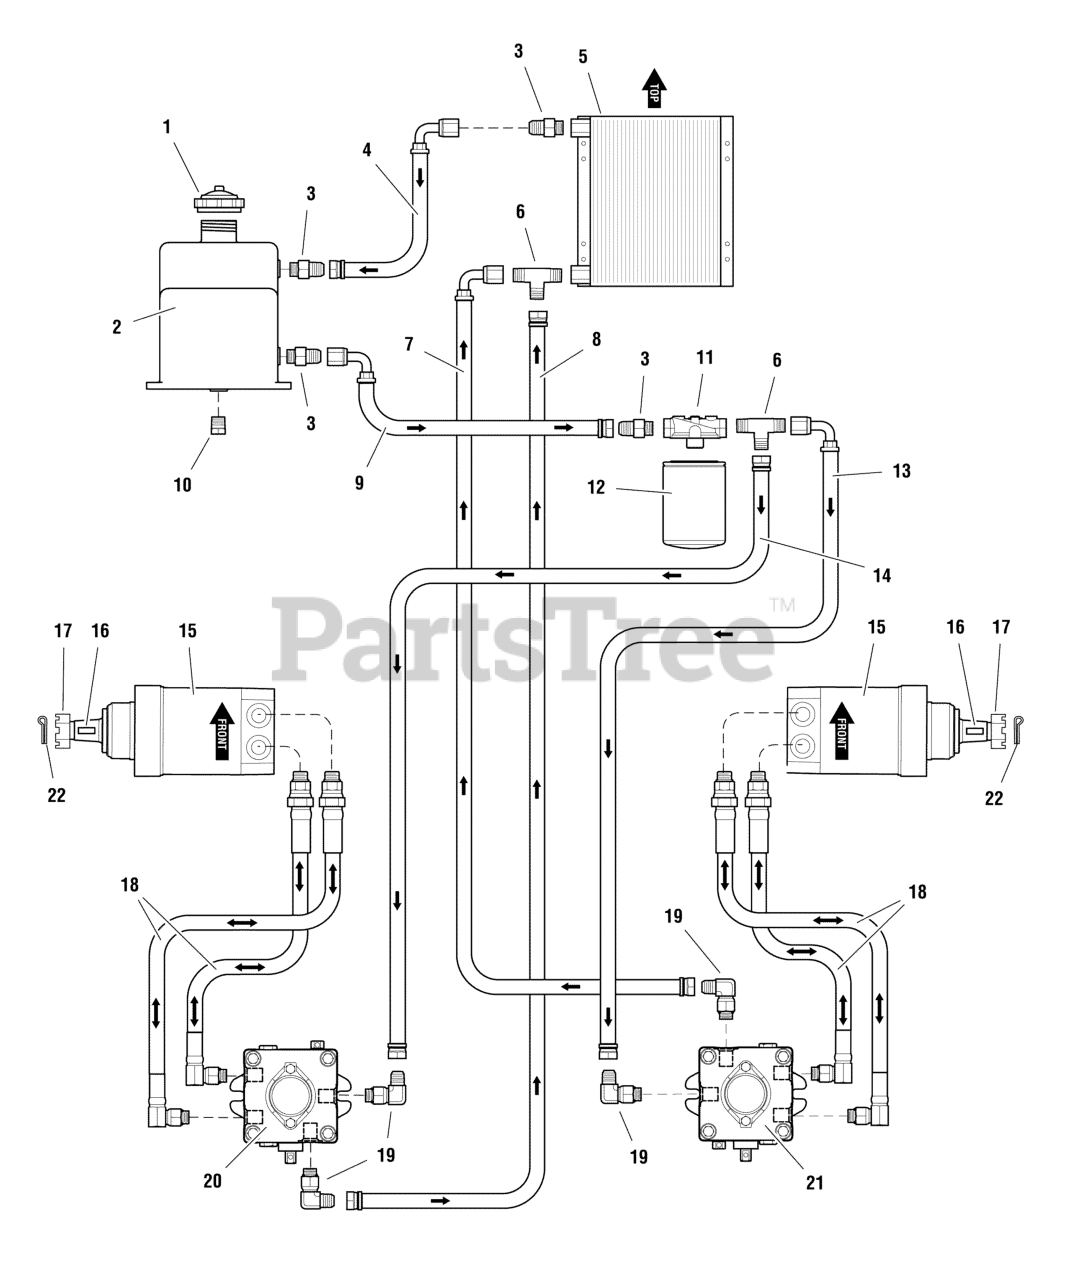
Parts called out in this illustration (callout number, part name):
1	CAP, Reservoir
2	HYDRAULIC OIL RESERVOIR
3	FITTING, NPT - JIC #8
4	HOSE ASSEMBLY (28")
5	OIL COOLER
6	FITTING, TEE, JIC #8, NPT
7	HOSE ASSEMBLY (31")
8	HOSE ASSEMBLY (34")
9	HOSE ASSEMBLY (9")
10	PLUG, 1/2" NPT
11	FILTER HEAD
12	FILTER, HYDRAULIC, SERVICE PART (PKG)
13	HOSE ASSEMBLY (24")
14	HOSE ASSEMBLY (40")
15	HYDRAULIC WHEEL MOTOR, Complete
16	KEY
17	NUT, CASTLE, 1-20
19	FITTING, O-Ring, 90 Deg.
20	HYDRAULIC PUMP - LH
21	HYDRAULIC PUMP - RH
22	PIN, COTTER, 1/8" X 2"
